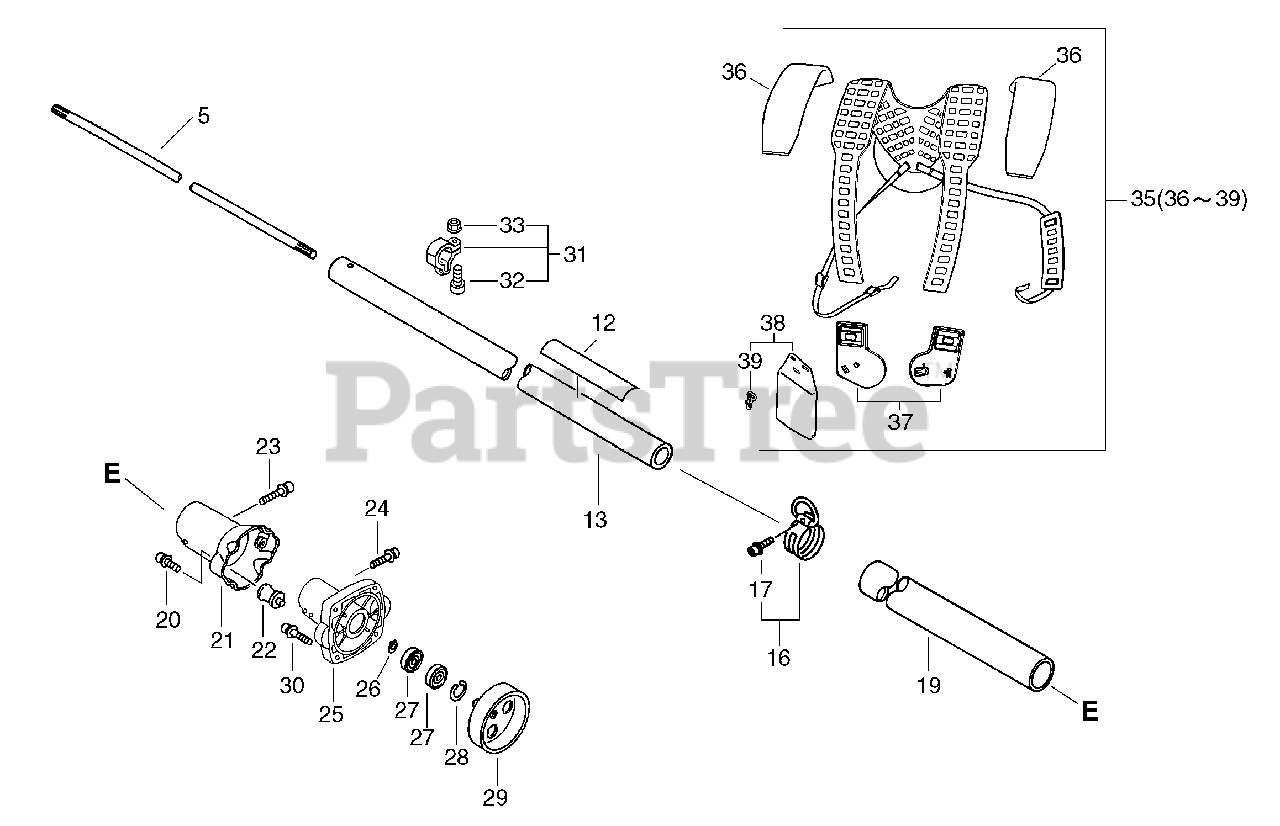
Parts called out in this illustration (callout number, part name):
5	DRIVESHAFT
12	LABEL - CAUTION
13	PIPE, MAIN
16	HANGER KIT
17	SCREW - 5X20
19	SWIVEL, D.S.HOUS
20	SCREW - 5X14
21	CLAMP, MAIN PIPE
23	SCREW - 5X35
24	SCREW - 5X30
25	CASE, CLUTCH
26	RING, RETAINING - 15
27	BEARING, BALL - 6202
28	RING, RETAINING - 35
29	DRUM, CLUTCH
30	SCREW - 5X25
31	HOOK ASSY
32	SCREW - 5X22
33	NUT - 5 -- FLANGE
35	HARNESS, SHOULDER
36	SHOULDER, PROTECTION
37	PLATE, LOCK - ORANGE
38	HIP PAD ASSY
39	HOOK
